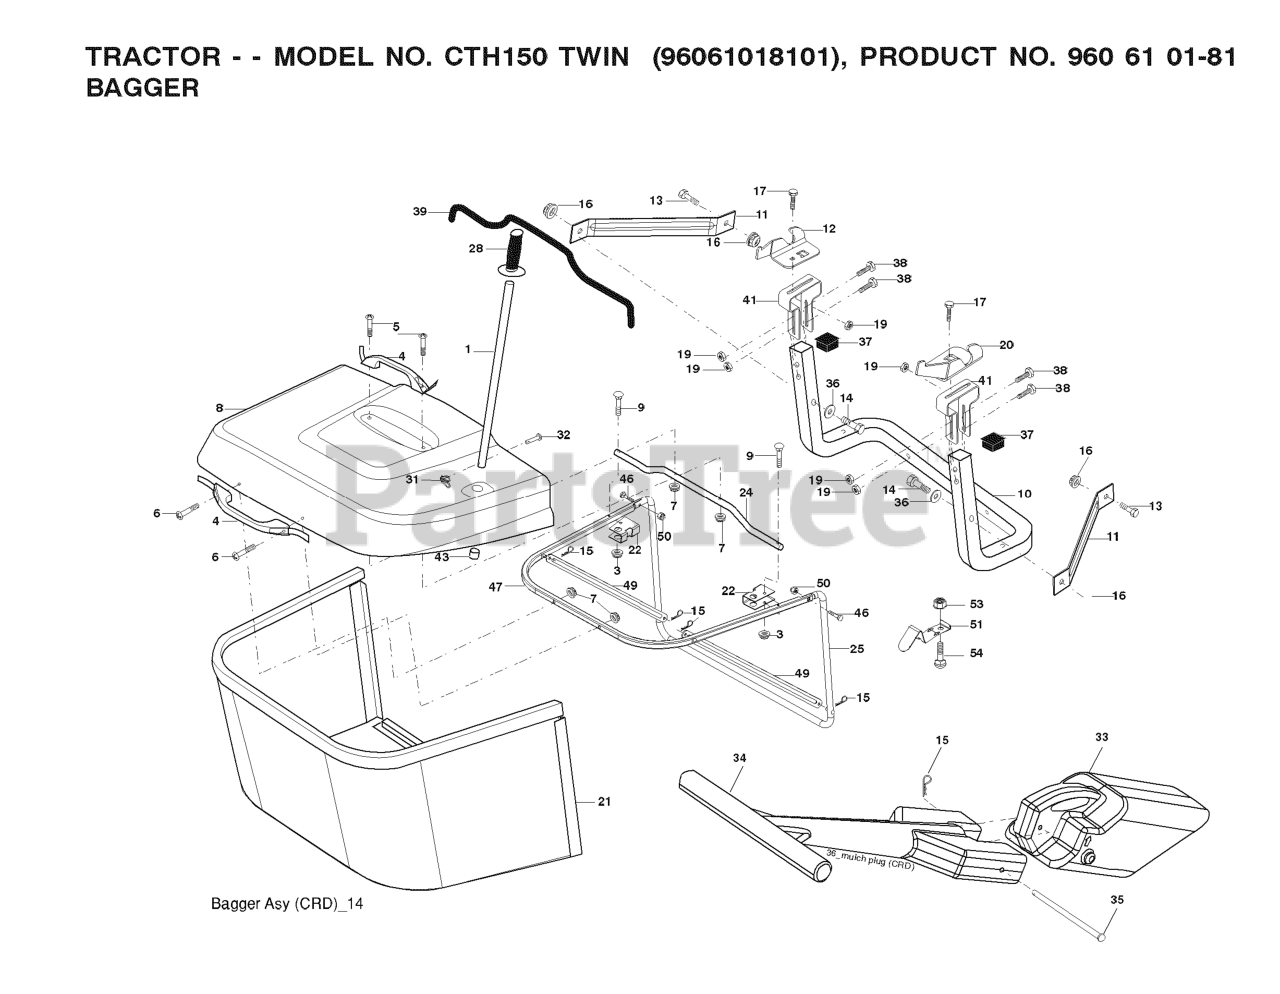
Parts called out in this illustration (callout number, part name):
1	TUBE HANDLE
3	NUT T
4	HANDLE.BAGGER.W/LVRS.BLK.CRD
5	SCREW.PAN.HEAD
6	REPL BY 532 75 00-29
8	COVER.PNT.BGR.CRD.WSLOTS.MS668
9	Bolt Carriage 1/4-20 x 2.25d x Gr.5
10	TUBE
11	BRACKET.SUPPORT.UPPER.BAG.CRD
12	BRKT PIVOT
14	BOLT-HEX EAK
15	RETAINER-SPRNG RB
16	NUT LOCK FLG 3/8-16 UNC
17	RP BOLT 5/16-18 X3/4 ZN/YEL GR
19	NUT LOCK HEX FLANGE 5/16-18
20	BRKT.PIVOT.RH.CRD
21	BAGGER.ASM.CRD.2007
22	BRKT.SIDE.BAG.CRD
24	TUBE.PIVOT.BAG.CRD.BLACK
25	PIPE
28	GRIP.HANDLE.BLACK
31	RETAINER CLIP
32	RIVET,DRILLED
33	MULCH PLUG, CTH150
34	HANDLE.MULCHER.92.CRD (2 2)
36	WASHER
37	Plug Support Bagger CRD
38	BOLT.5/16-18X2.5
39	SEAL.TRIM.37'
41	BRKT.VERT.ADJ.BAGGER.CRD
43	PLUG, TUBING END
46	BOLT.CARRIAGE.5/16-18
47	PIPE
49	ROD
50	NUT.71038.31-18.HEX.NYLOCK
51	LATCH
53	NUT
54	BOLT
